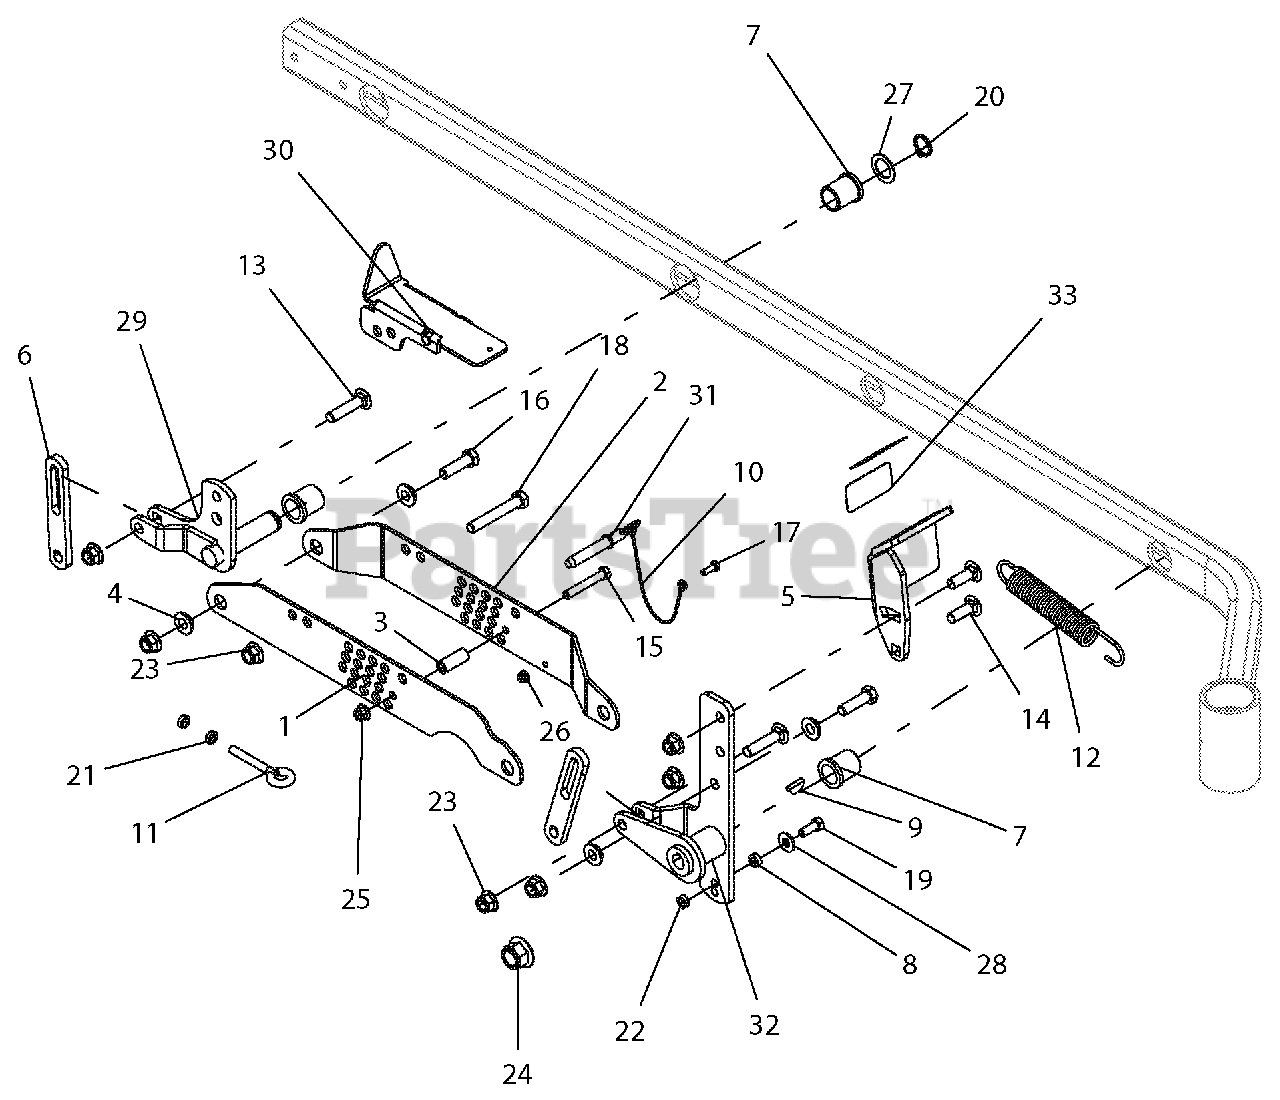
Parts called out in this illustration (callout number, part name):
1	BRKT, RH OUTBOARD LIFT/CUT HEIGHT-BLACK
2	BRKT, RH INBOARD LIFT/CUT HEIGHT-BLACK
3	SPACER, .375 X .625 X 1.54
4	BSHG, FLANGE .515X.750X.31X1.12
5	PEDAL, ADJUSTABLE FOOT LIFT-BLACK
6	LINK, DECK LIFT - LONG
7	BSHG-FLG 1.00X1.25X1.5X1.5
8	BSHG, SLV .377X.624X.235
9	KEY, WDRF .25 X 1.00 HRD #15
10	LANYARD, 12"
11	BOLT, EYE .375-16
12	SPRG, TENSION .162 X 1.250 X 8.250
13	BLT-RDHDSQNK .50-13X2.25 G5 Y
14	BLT-RDHDSQNK .50-13X1.50 G5 YWZC
15	BLT-HEX .38-16X2.50 GR5 YWZC
16	BLT-HEX .50-13X1.75 GR5 YWZC
17	BLT-HEX .25-20X.75 GR5 YWZC
18	BLT-HEX .50-13X3.25 GR5 YWZC
19	BLT-HEX .38-16X1.00 GR5 YWZC
20	RG-RTNG-EXT 1.00X.078
21	NUT, JAM .375-16 YWZC
22	@NUT-LK-CTR-JAM .375-16 YWZC
23	NUT-LK-NYL-FLG .50-13 YWZC
24	NUT-LK-NYL-FLG .75-10 YWZC
25	NUT-LK-NYL-FLG .38-16 YWZC
26	NUT-LK-NYL-FLG .25-20 YWZC
27	WSHR-FL-STL 1.010X1.505X.062 YWZC
28	WSHR-FL-STL.438X1.00X.083 YWZC
29	WLDMT, RH REAR DECK LIFT
30	WLDMT, MECHANICAL LOCK-UP-BLACK
31	PIN, .50 X 2.00 USABLE LG BALL
32	WLDMT, TAPERED LIFT ARM FRONT LH-BLACK
33	GRIP, PEDAL 1.50 X 3.00
